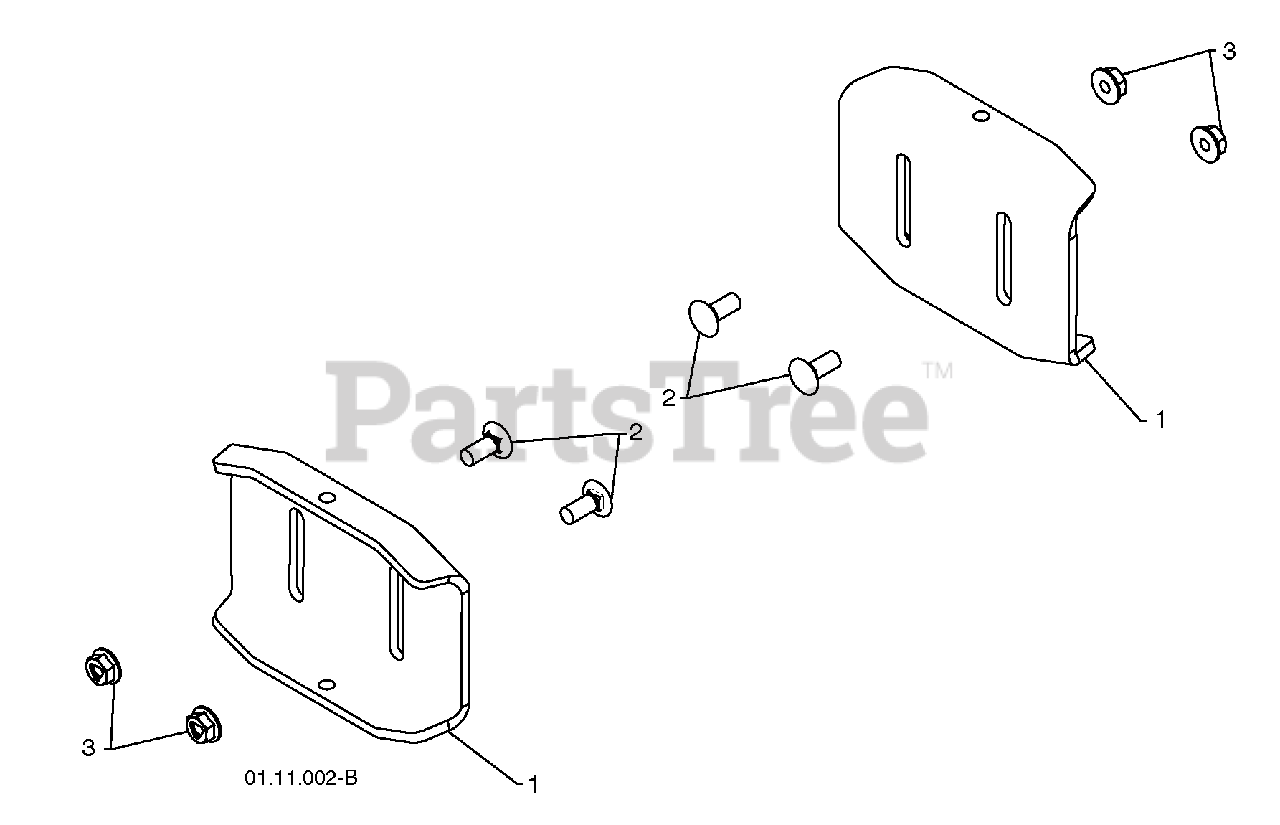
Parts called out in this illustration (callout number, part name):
1	SKID PLATE
2	CARRIAGE BOLT 5/16-18 X .750
3	NUT 5/16-18
